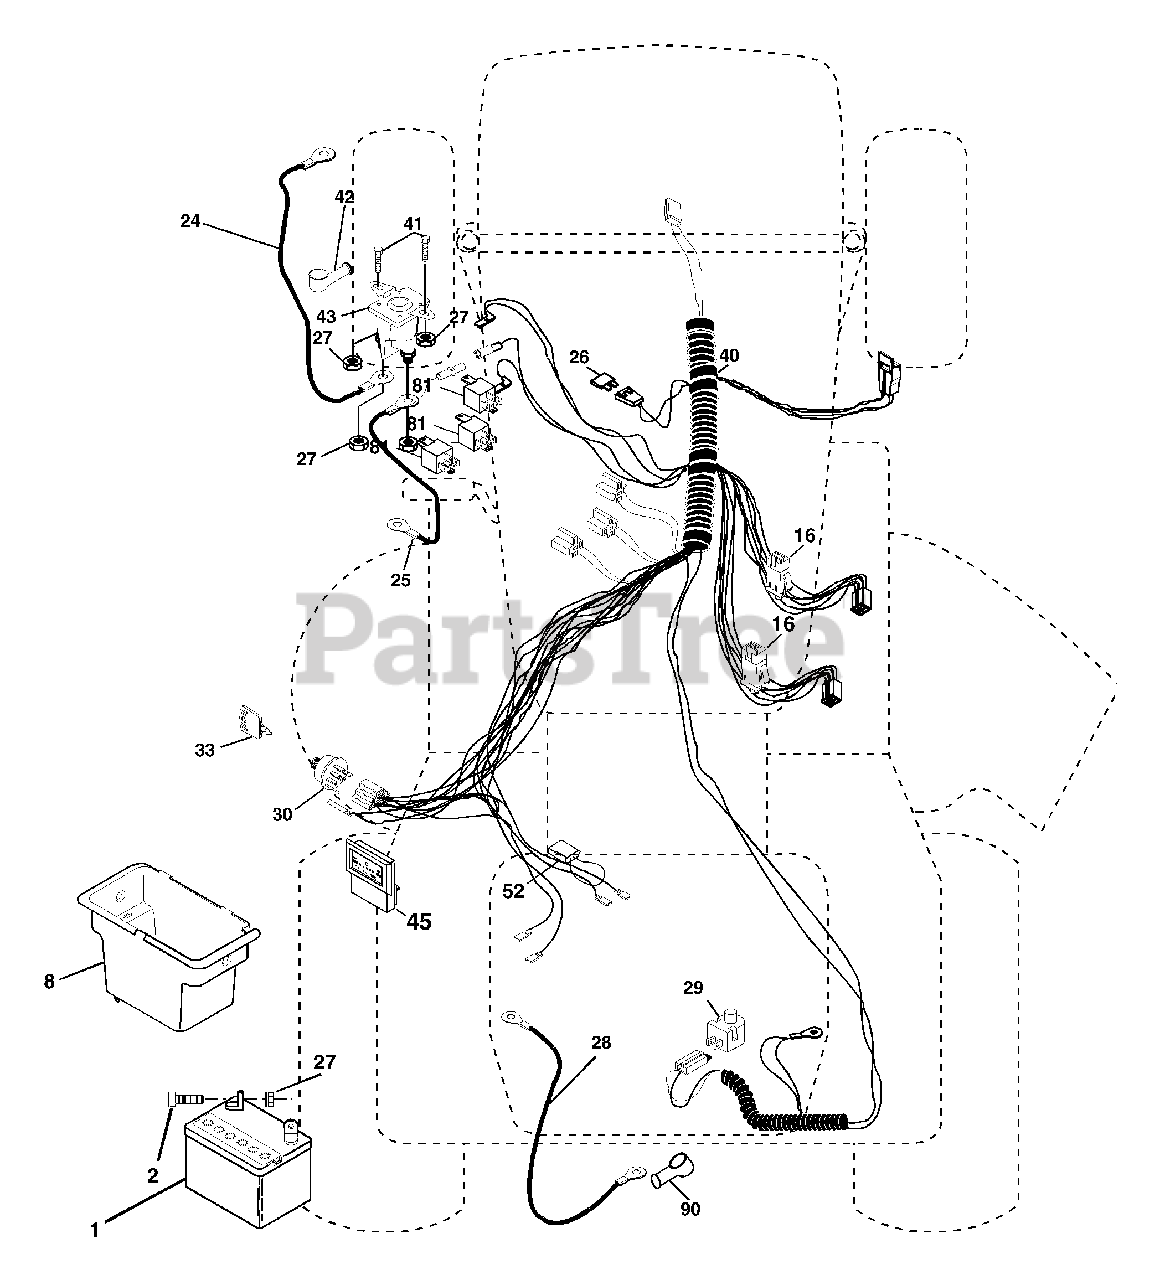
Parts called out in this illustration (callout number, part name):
1	Battery 12 Volt 25 Amp
2	Bolt Hex Hd 1/4-20unc X 3/4
8	Box Battery
16	Switch Interlock
21	Harness Asm Light W/4152J
22	Bulb Light #1156
24	Cable Battery 6 Ga 11" red
25	Cable Battery 6 Ga w/16 wire,red
26	Fuse 20 AMP
27	Nut Keps Hex 1/4-20 unc
28	Cable Ground 6 Ga 12" black
29	Switch Plunger
30	Switch Ign
33	Key Ign
40	Harness Ign
41	Bolt Blk Fin Hex 1/4-20 X 1/2
42	Cover Terminal Red
43	Solenoid
45	Ammeter
52	Protection Wire Loop
81	Relay Asm.
90	Cover Terminal
